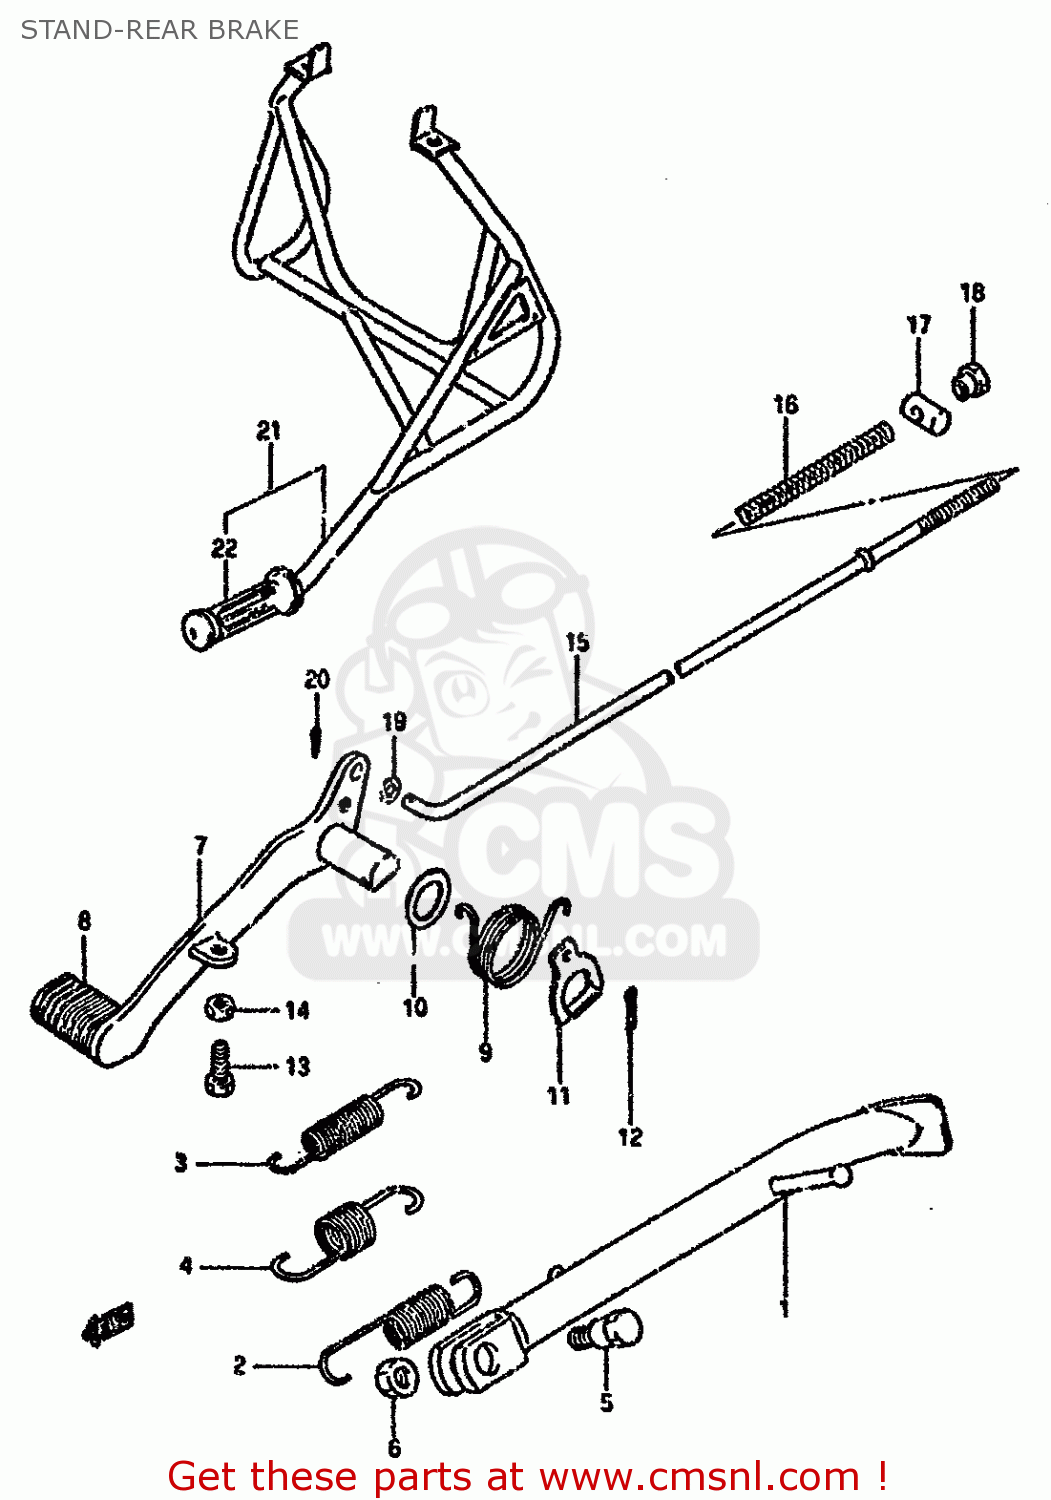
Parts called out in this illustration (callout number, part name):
1	STAND,PROP
2	SPRING
3	SPRING
4	SPRING
5	BOLT(10X28)
6	NUT
7	PEDAL,BRAKE
8	RUBBER,PEDAL
9	SPRING,BRAKE PEDAL RETURN
10	WASHER
11	BRACKET,STOP LAMP SWITCH
12	COTTER PIN
13	BOLT
14	NUT
15	ROD ASSY,RR BRAKE
16	SPRING
17	PIN(11X18)
18	NUT (6MM)
19	WASHER
20	PIN
21	STAND ASSY, REAR
22	GRIP,L
